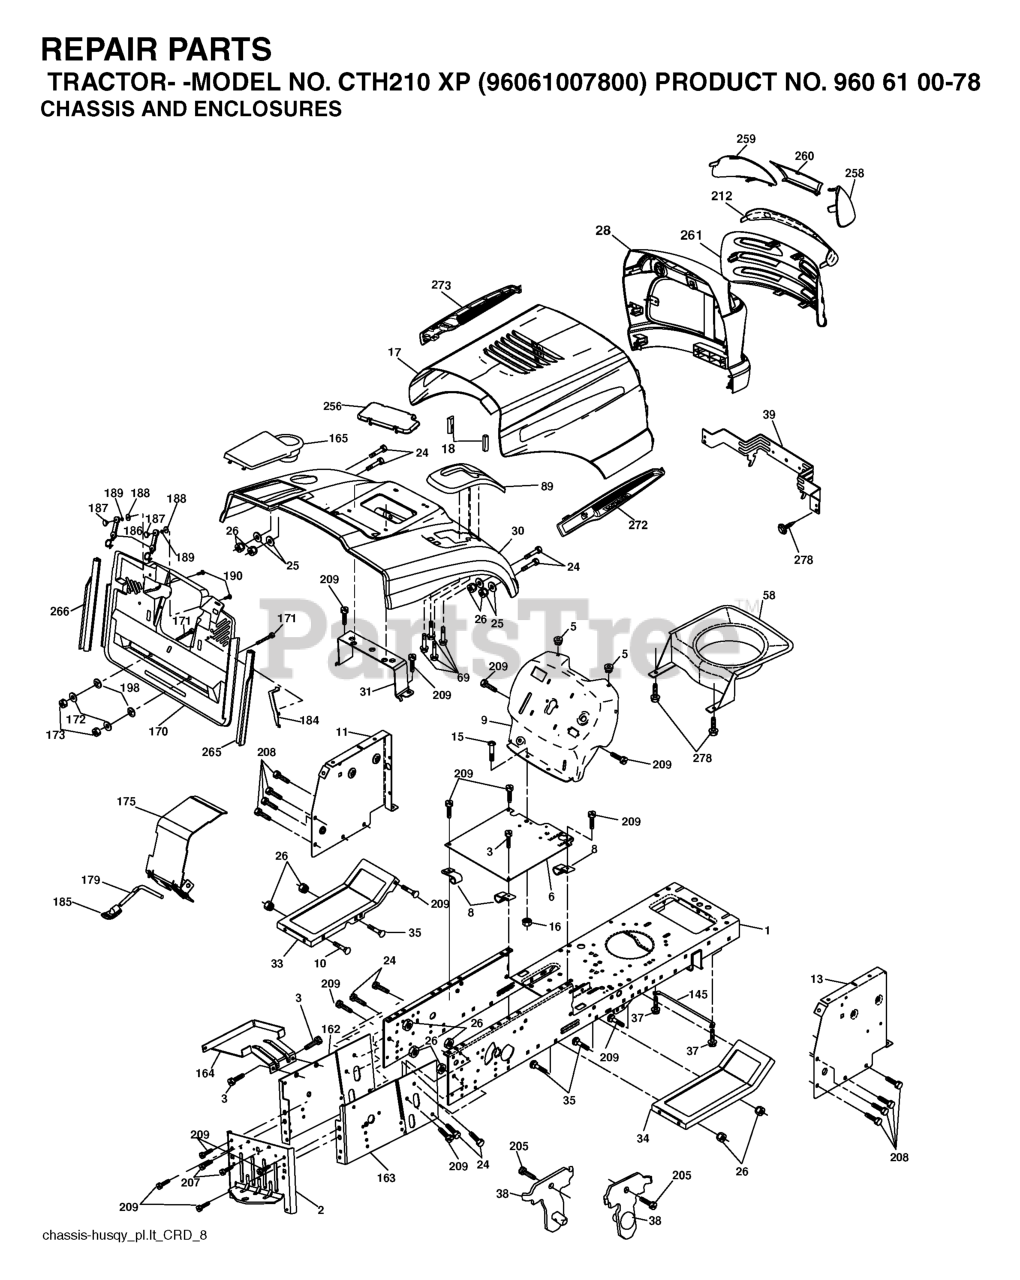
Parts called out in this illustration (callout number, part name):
2	DRAWBAR
3	SCREW 3/8-16X3/4
5	BUMPER.RUBBER.HOOD
6	PLATE
8	CLIP,INSULATOR
9	DASH.SLKSCR.STL.PLM
10	BOLT D
11	PANEL.DASH.LH.LTX
13	PANEL ASM, DASH RH
15	Screw, Machine, Truss Head 5/16-18 UNC x 3/4
16	NUT
17	VENT.HOOD.LASER.III
18	BUMPER.HOOD.LARGE.1.75"
25	WASHER
26	NUT
30	CONSOLE.CRD.AUTO.GRY
31	BRACKET SUPPORT FENDER
33	FOOTREST PNT LH
34	FOOTREST PNT RH
37	Screw 5/16-18 x 1/2 Hex, Self Tapping 5/16-18 x 1/2
38	BRACKET ASM PIVOT MOWER REAR
39	BRACKET PIVOT LASER
69	SCREW.HI-LO.CONSOLE
89	CONSOLE.CRD.AUTO.GREY.2005
145	ROD PIVOT CHASSIS/HOOD
162	BRACKET
163	BRACKET EXTEN CHASSIS RH CRD
165	RP.COVER.BATTERY.CRD.GREY
172	WASHER
175	DOOR TRAP
179	ROD PIVOT FBI
184	BRACKET.ACTUATOR.BAGGER.SRD
186	LATCH ASSY
187	WELDNUT
189	LOCKWASHER #10
190	SCREW
207	SCREW, 5/16-18 X 1/2
208	SCREW 3/8-16X1/2
209	SCREW, 3/8-16X3/4
212	INSERT.LENS.REFLECTIVE
256	COVER FENDER CRD
258	LENS LH
259	LENS LH
260	COVER.LENS.HUSQ.LASER
265	SEALING
266	SEALING
272	VENT.HOOD.LASER.
273	VENT.HOOD.LASER.
278	SCREW
